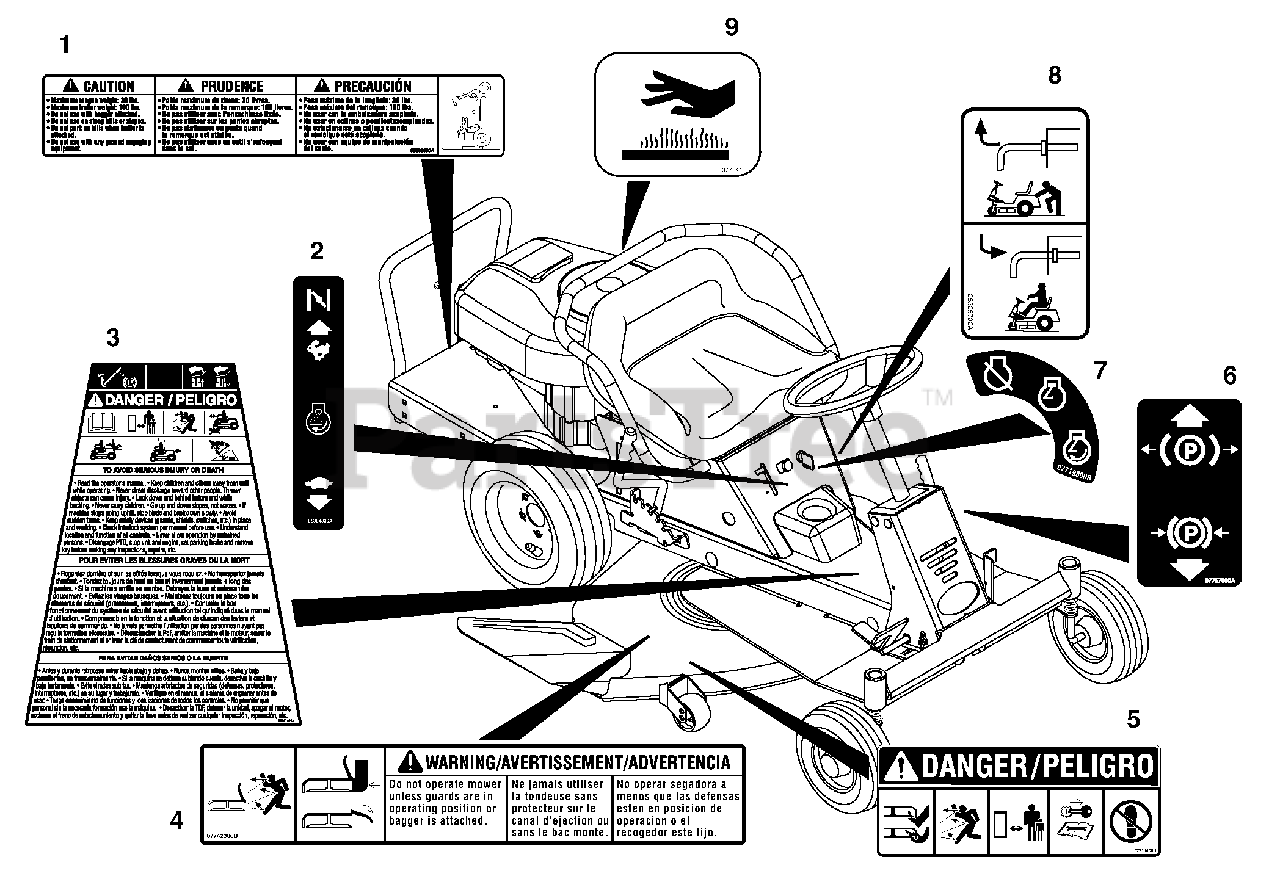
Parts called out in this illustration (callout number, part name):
1	Decal, Trailer Hitch
2	Decal-Throttle
3	Decal-Rear Engine Rider Warning
4	Decal, Warning
5	Decal, Mower Pan Danger
6	Decal, Parking Brake Lever
7	Decal- Ignition
8	Decal, Transmission Disconnect
9	Decal, Hot Surface
